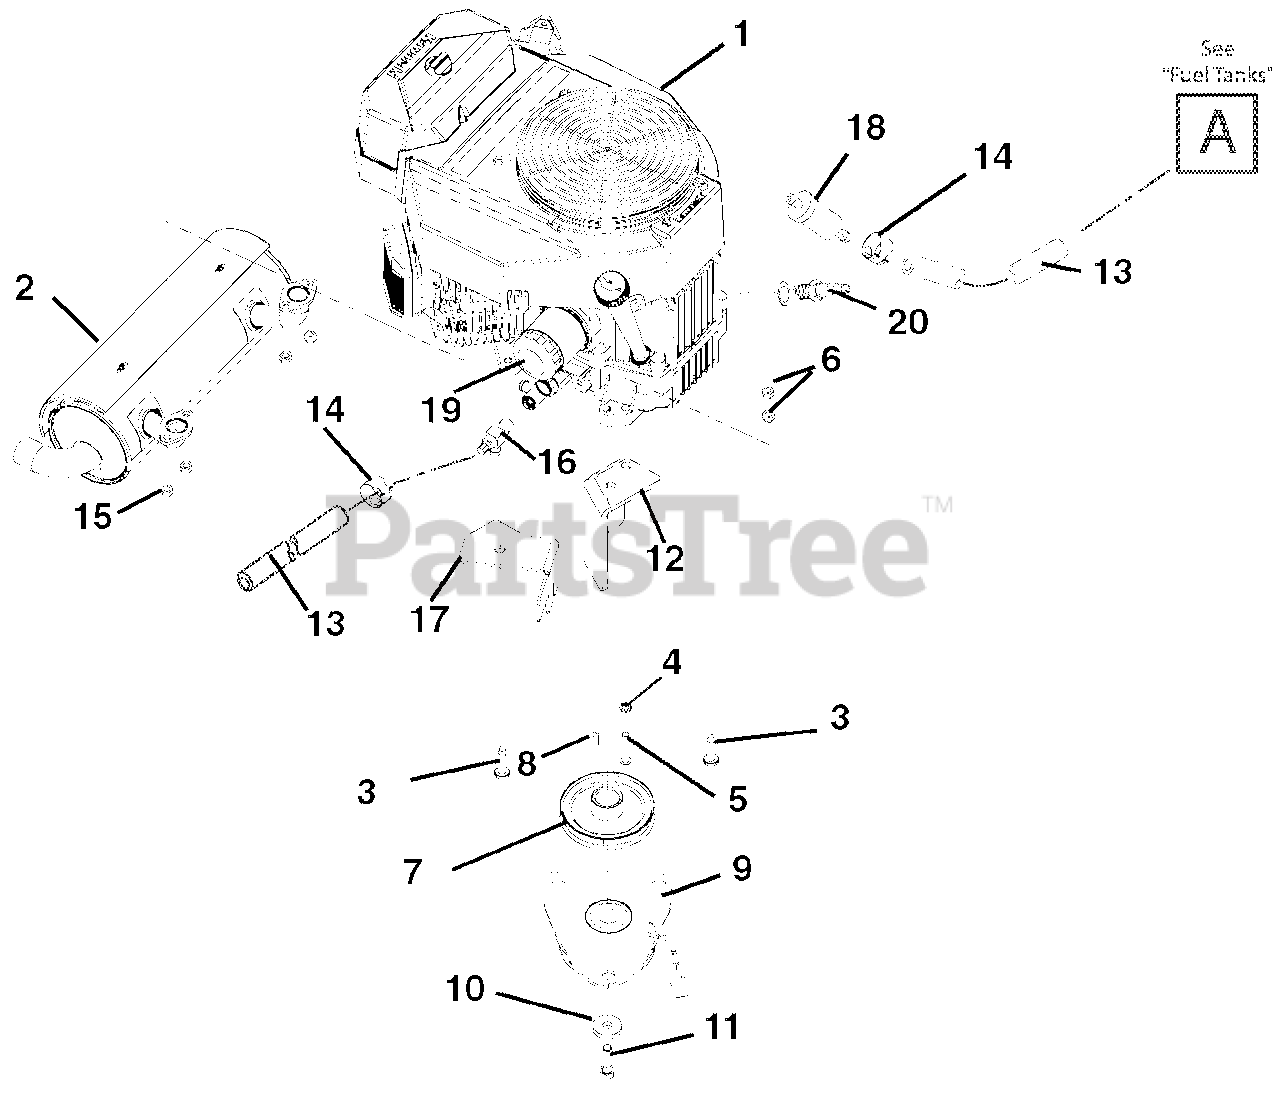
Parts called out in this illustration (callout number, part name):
1	Engine, Kawasaki FH451V
2	Muffler, Kawasaki
3	Screw, Tapping Hex Washer Head .38-16 x 1.50
4	Washer, Locking-EXT.326 x .599 x .031
5	Bolt, Button Head .31-18 x 1.75
6	Nut, Locking-Center .31-18
7	Sheave, 4.831 x 1.127
8	Key, Square .25 x .625 x .25 SAE 8630 OR SAE 1035
9	Clutch, Ogura GT1A
10	Washer, Flat-Steel .469 x 2.00 x .25
11	Bolt, Hex .44-20 x 1.50 Grade 5 EP80
12	Anchor, Ogura Clutch
13	Hose, Gas Line Low Perm
14	Clamp, Fuel Line
15	Nut, Top Lock M8-1.25
16	Drain, .50 Oil
17	Guard, Clutch Wire
18	Fuel Filter, Kawasaki
19	Oil Filter, Kawasaki
20	Spark Plug, Kawasaki
